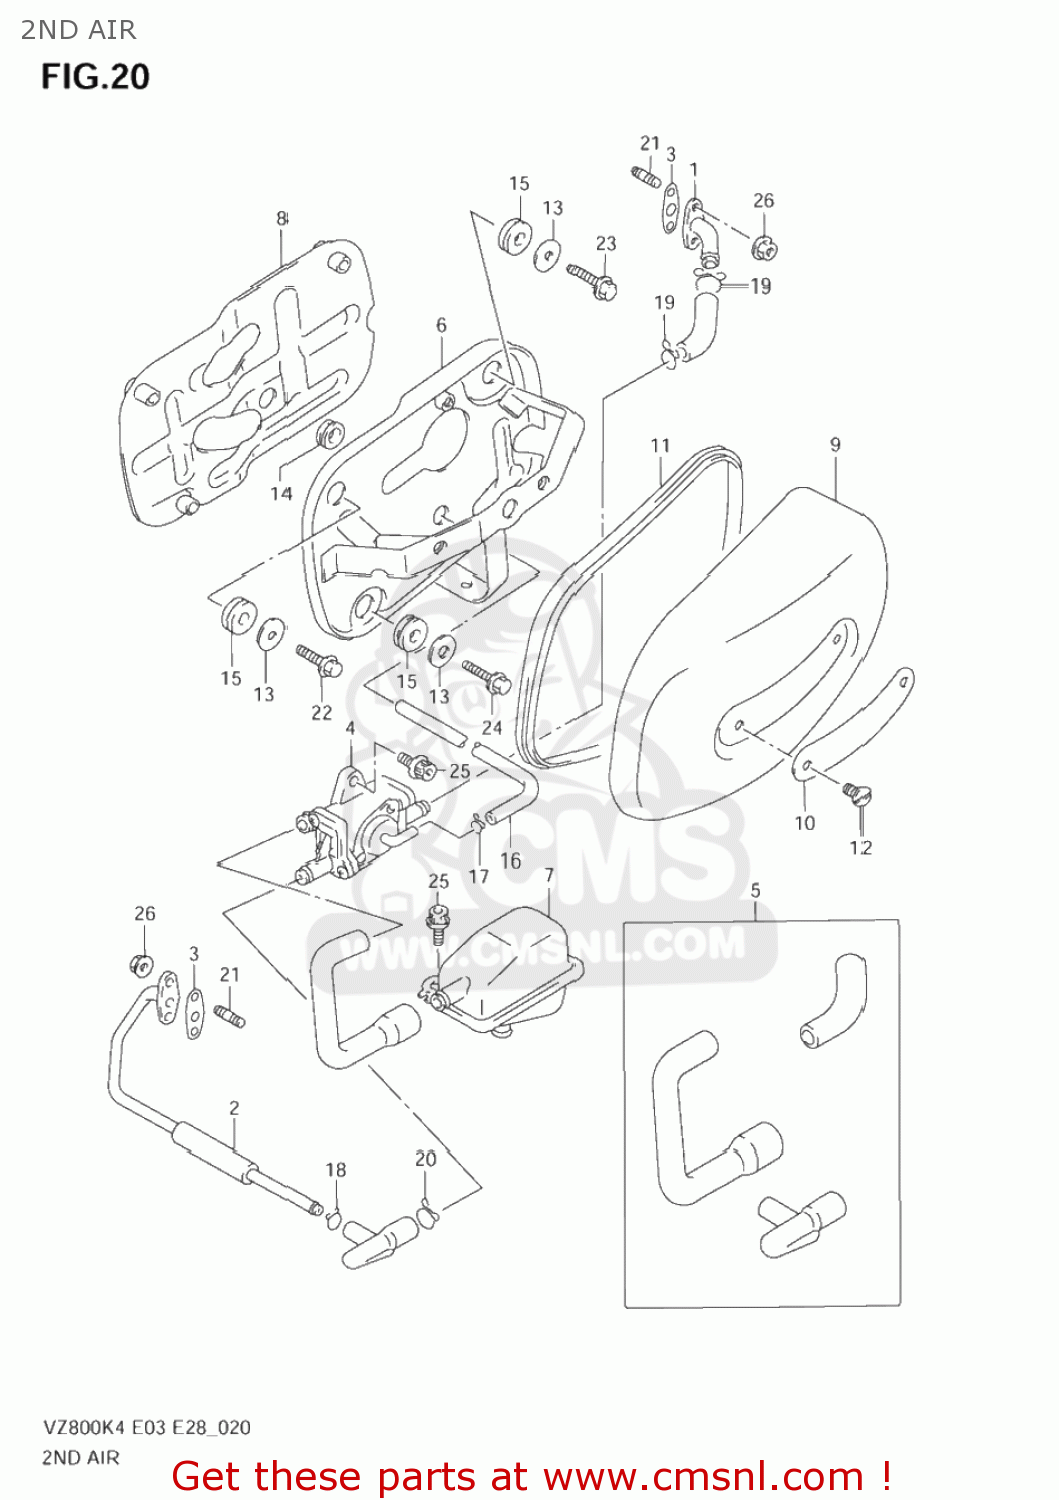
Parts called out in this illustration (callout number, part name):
1	PIPE,2ND AIR FR
2	PIPE,2ND AIR RR
3	GASKET,2ND AIR PIPE (NAS)
4	VALVE ASSY,2ND AIR
5	HOSE SET,2ND AIR
6	BRACKET,2ND AIR SPRT
7	CLEANER,2ND AIR
8	PLATE,2ND AIR HEAT GUARD
9	COVER ASSY,2ND AIR
10	WASHER,2ND AIR COV
11	CUSHION
12	SCREW(6X12)
13	WASHER
14	CUSHION
15	CUSHION
16	HOSE(4X7X600)
17	CLIP
18	CLIP
19	CLIP
20	CLIP
21	STUD BOLT
22	BOLT
23	BOLT
24	BOLT
25	BOLT MAGNETO S
26	NUT
